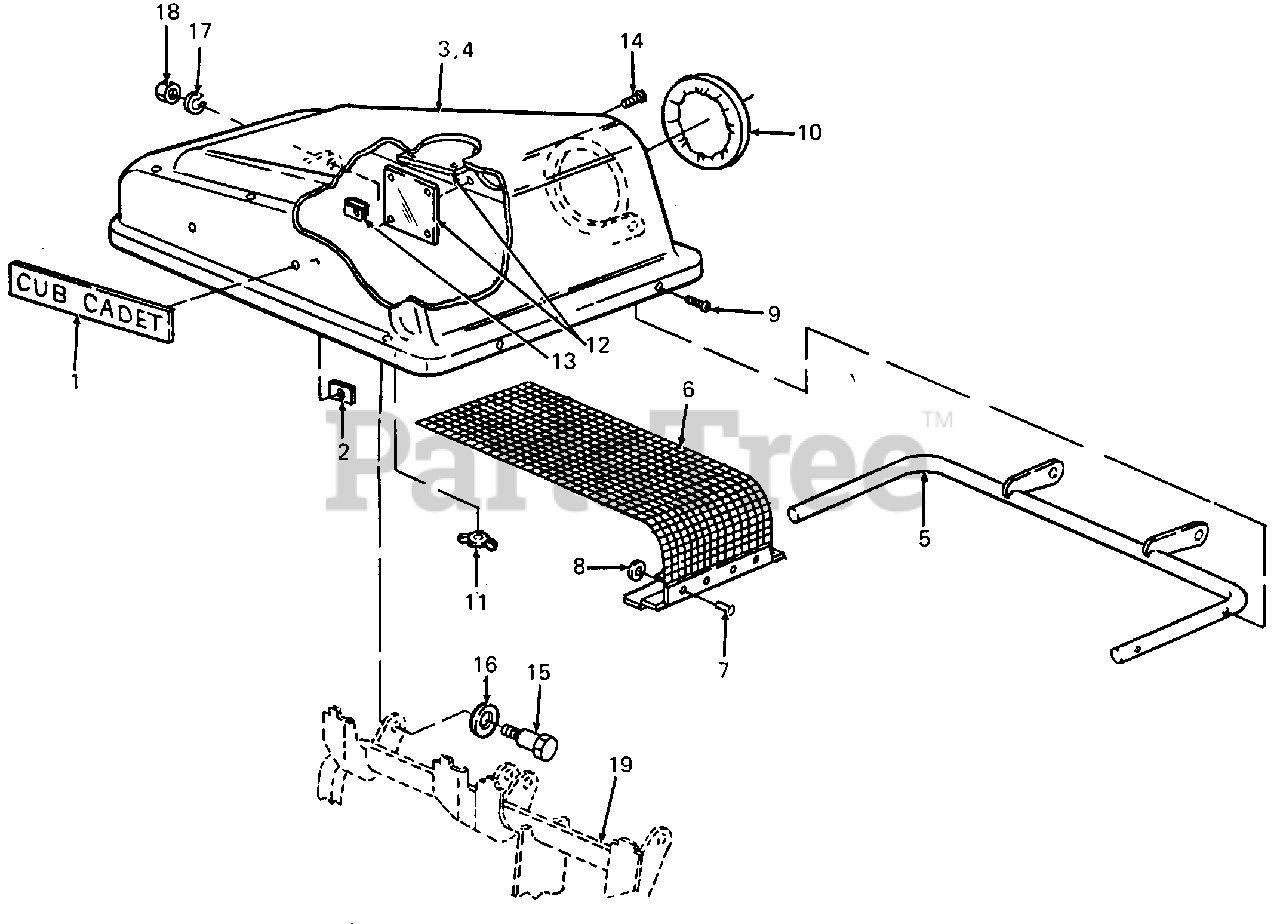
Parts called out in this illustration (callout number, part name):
1	Plaque, Logo w/Studs
2	Nut, Push-on Speed
3	Cover Assy, Grass Catcher
4	Cover w/Holes, Grass Catcher
6	Screen Assy
7	Rivet, Pop
8	Washer, Flat, .218 X .62 X .063
9	Screw, Hex Wash. Hd. Tapp, 1/4 X .50 Lg
10	Seal, Tube, 7.1 ID
11	Twist Fastener, Zip
12	Plate, Plastic, 1/8 Thk X 5.62 Sq
13	Nut, U-Type Speed
14	Screw, Truss Mach., #10 X .50 Lg
15	Screw, Shld
16	Washer, Bell, .505 X 1.0 X .075 Thk
17	Washer, Lock, 3/8
18	Nut, Hex, 3/8-16
19	Tube Assy, Catcher Support
